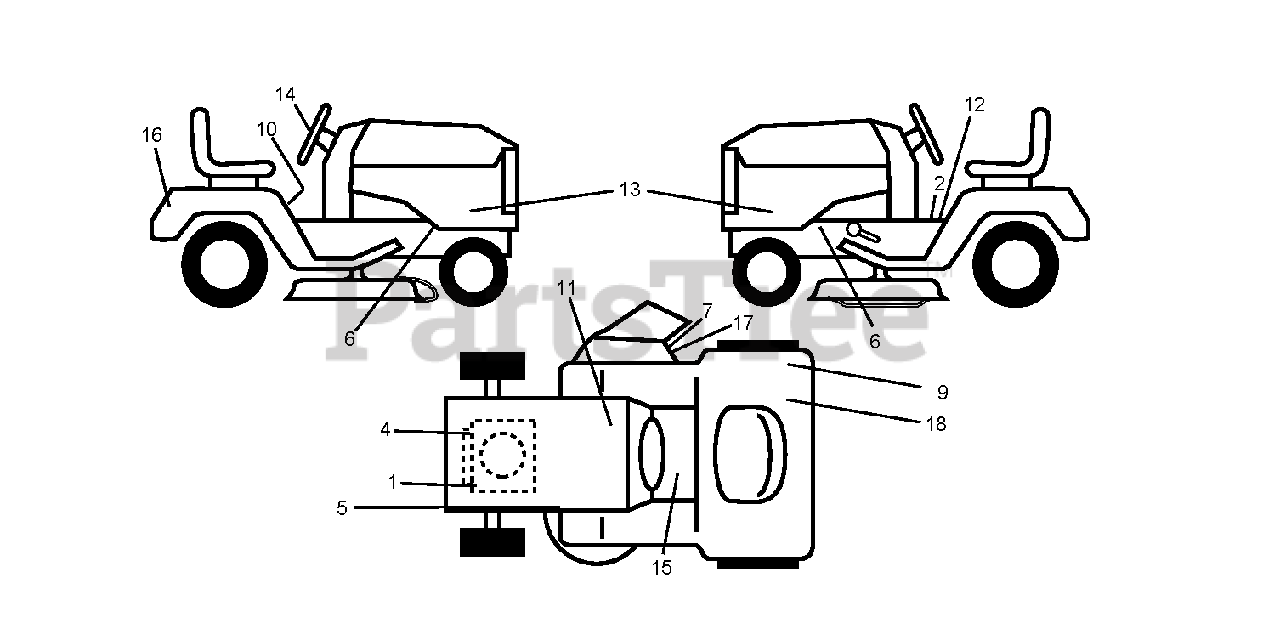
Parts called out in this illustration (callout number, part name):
2	DECAL PARK BRAKE
5	DECAL V BELT SCHEMATIC
7	DECAL.INTERNATIONL.CUTFINGER
11	DECAL BTRY SYMBOLS
17	DECAL, DEFLECT WARNING
18	DECAL.80 DBA.AUSTRALIA
